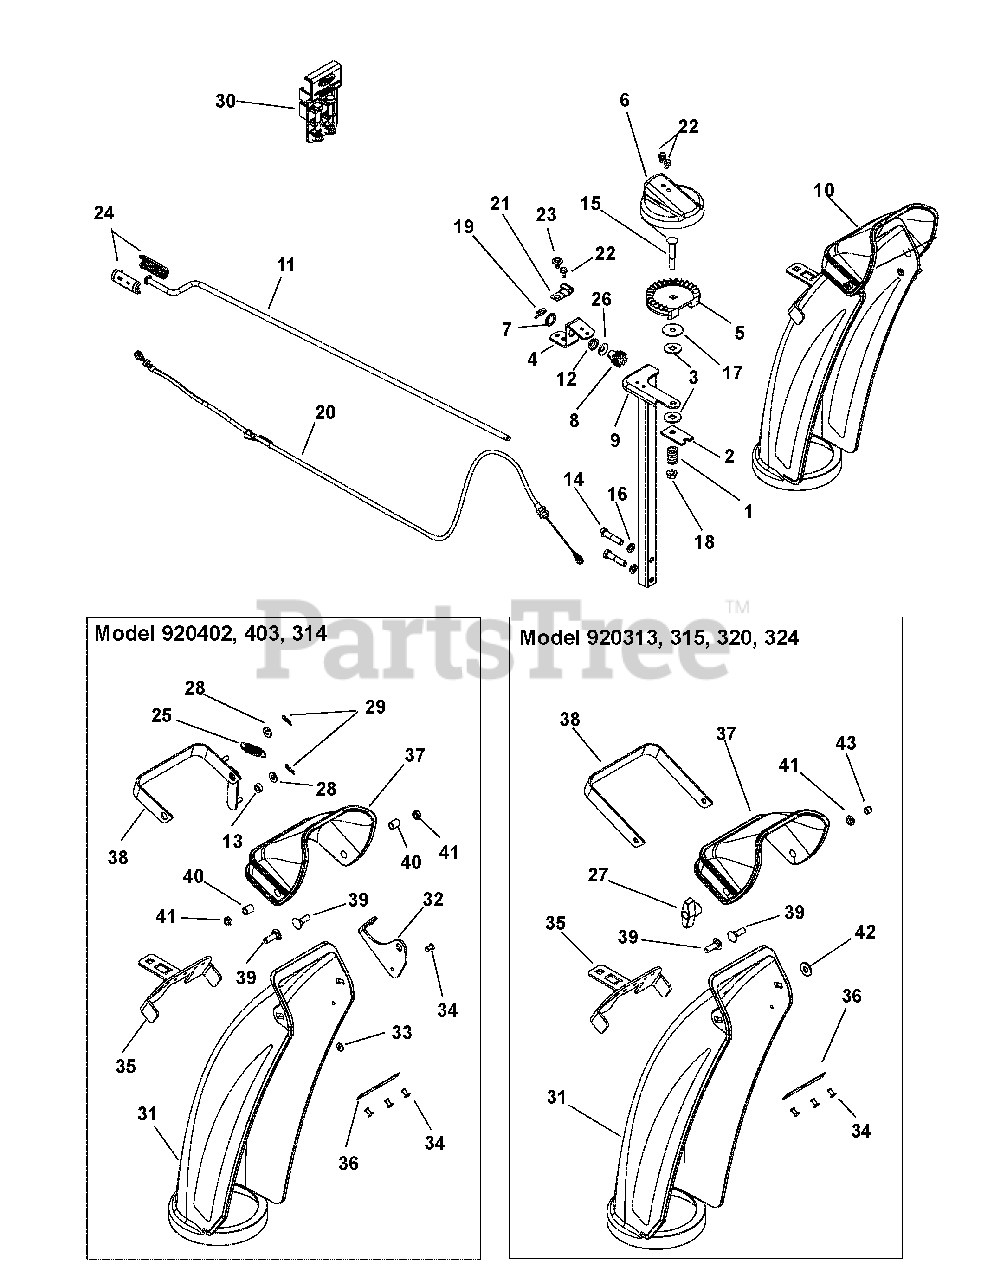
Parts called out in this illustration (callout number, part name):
1	SG-COMP .187X.56X1.62
2	PLATE, FRICTION
3	FRICTION WASHER
4	BRACKET, PINION GEAR
5	CHUTE GEAR
6	GEAR COVER
7	PUSHNUT .625
8	PINION GEAR W/BRACKET
9	CHUTE PEDESTAL, TALL COMPACT
10	CHUTE, REMOTE DISCHARGE W/CAP
10	CHUTE, MANUAL DISCHARGE W/CAP
11	ROD, CHUTE CRANK, COMP&SNOTEK
12	BUSHING, POLYLINER-.63 SNAPIN
13	BSHG-SLV .265X.500X.219
14	@BLT-HEX .38-16X1.75 GR5 YWZC
15	@BLT-RDHDSQNK .38-16X2.50 G5YZ
16	@WSHR-LK .38X.094 REG YWZC
17	@WSHR-FL-STL .406X1.25X.10 ZC
18	@NUT-LK-TOP-FLG .38-16 YWZC
19	PIN, SPRING CLIP
20	CABLE, DEFLECTOR CAP SNO-TEK
21	J-CLAMP
22	SCR-TAP .25-20X.50 HWH TR YWZ
23	SCR-TAP .25-20X.50 LGHWH TR YZ
24	KNOB, CHUTE CRANK - SNAP BLK
25	SPRG, TENSION .052X.520X1.74
26	WSHR-THRST .625 X 1.0 X .03
27	KNOB, WING .31-18 UNC
28	@WSHR-FL-STL.281X.62X.065 YWZC
29	PIN-HAIR INT .06X.18X.77
30	HOLDER W SMALL SHEAR BOLT /NUT
31	CHUTE, PLASTIC DISCHARGE LONG
32	BRACKET, CABLE ANCHOR SNOTEK
33	WSHR-FL-STL .196X.500X.06 YZ
34	RIVET, #66 STEEL POP PD BLACK
35	CHUTE MOUNT BRACKET
36	PLATE,CHUTE MOUNT BACKING
37	DEFLECTOR CAP, PLASTIC
38	WELDMENT, DEFLECTOR CAP SNOTEK
38	HANDLE, MANUAL CHUTE CAP
39	BLT,RNHDRECSHNK .31-18X1.00
40	BSHG-SLV .330X.455X.550
41	@NUT-LK-CTR-JAM .31-18 YWZC
42	@WSHR-FL-STL.38X.875X.083 YWZC
43	CAP, END .281X.313
